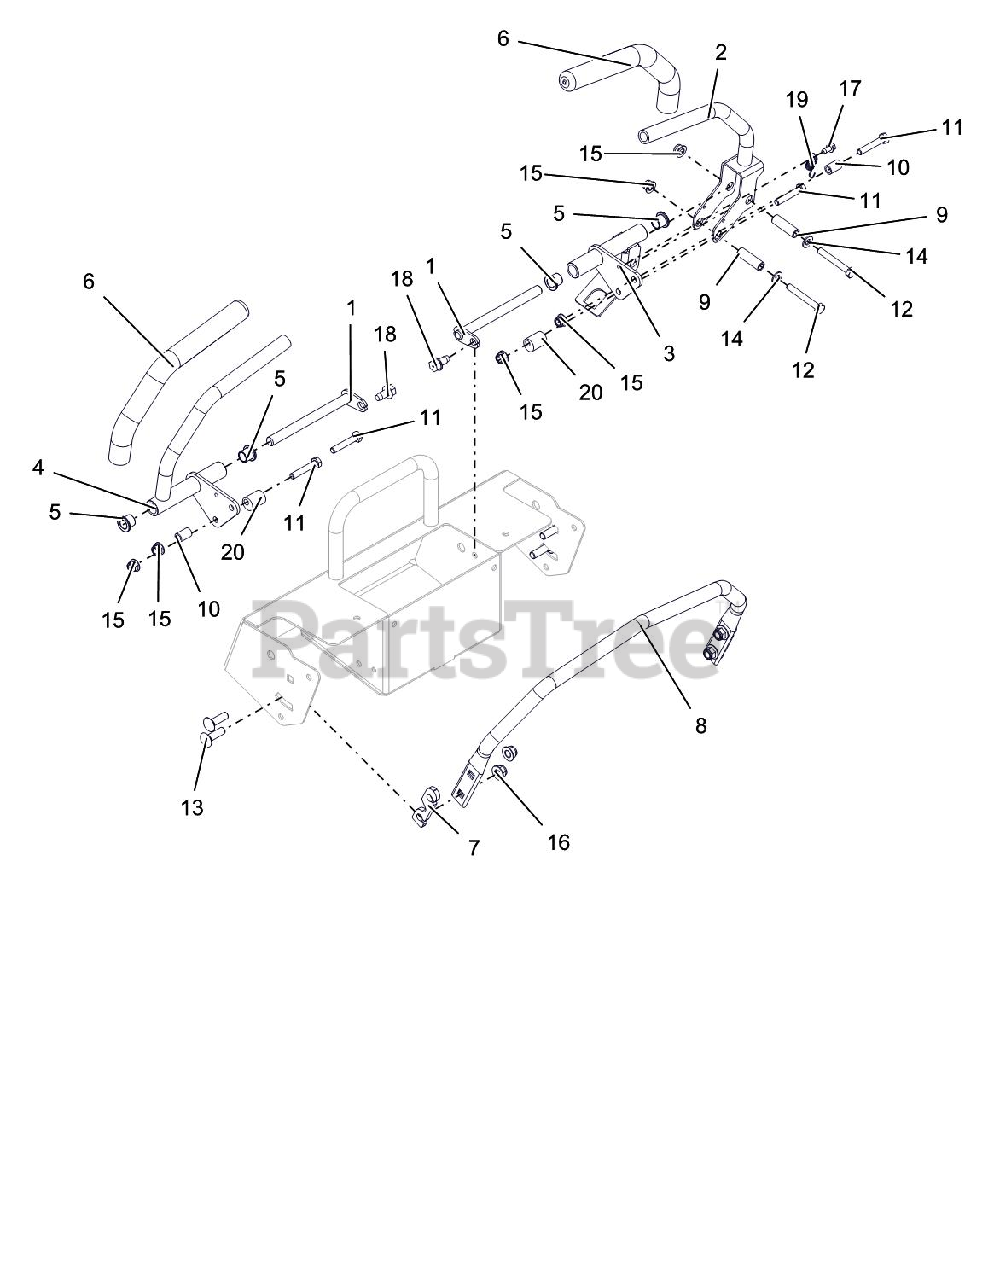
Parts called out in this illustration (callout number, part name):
1	WLDT, PIN AND LOCK Y
2	WMT, CONTROL ARM OPC
3	WMT, CONTROL ARM (LH)
4	WMT, CONTROL ARM (RH)
5	BRG, FLG .500X.620X.500 BRNZ
6	GRIP, HANDLEBAR
7	SHIM, 5 DEG SPEED BAR
8	BAR, FORWARD STOP PRO-STANCE
9	BSHG-SLV .325X.49X1.56
10	BSHG-SLV .328X.50X.75
11	@BLT-HEX .31-18X1.75 GR5 YWZC
12	@BLT-HEX .31-18X2.25 GR5 YWZC
13	@BLT-RDHDSQNK .38-16X1.25 G5YZ
14	@WSHR-FL-STL.344X.688X.065YWZC
15	@NUT-LK-NYL-FLG .31-18 YWZC
16	@NUT-LK-NYL-FLG .38-16 YWZC
17	SCR-TAP .25-20X.50 HWH TR YWZ
18	@SCR-TAP .38-16X.75 HWH TR YWZ
19	SPRING, EXT. .043X.438X1.64
20	ECCENTRIC
